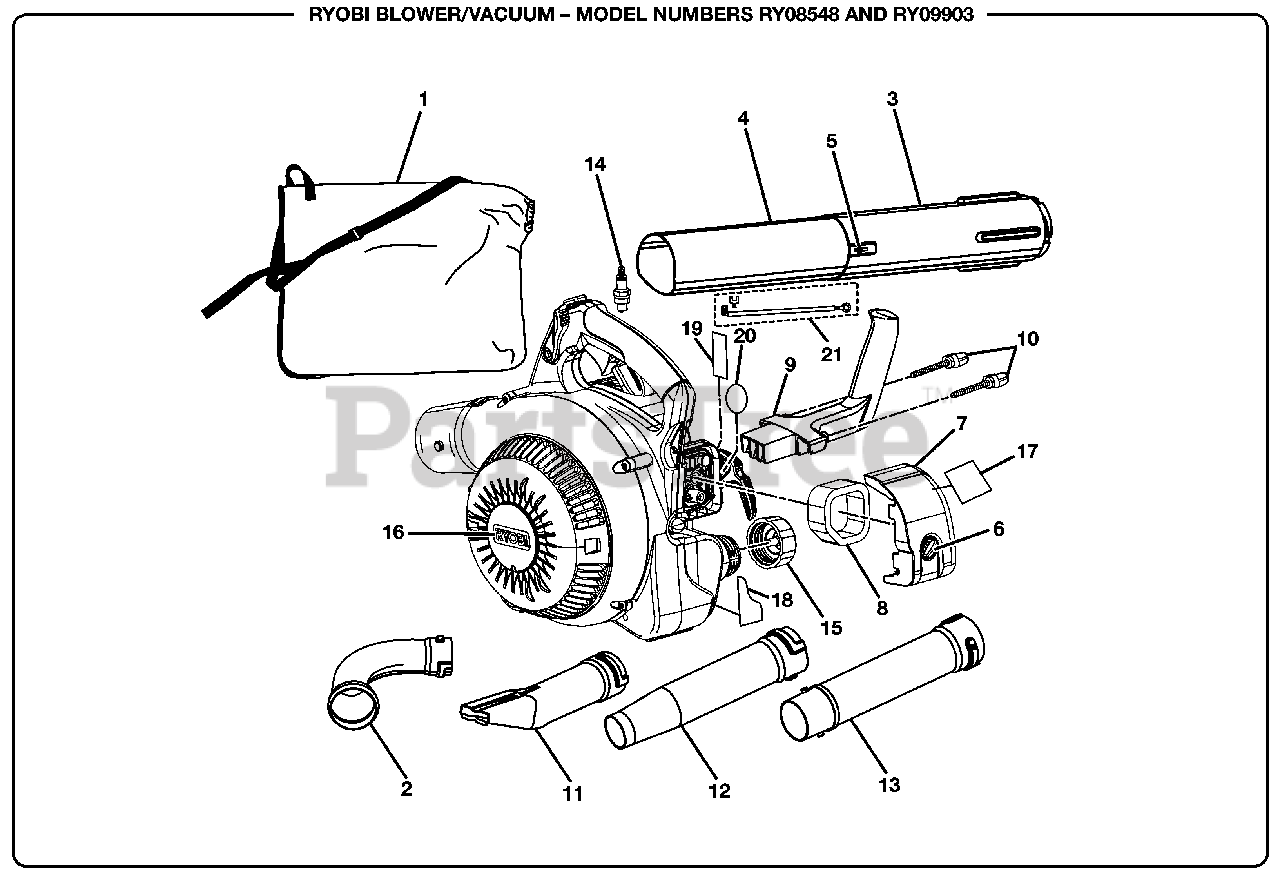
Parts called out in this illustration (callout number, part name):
1	Vacuum Bag w/Shoulder Strap
2	Vacuum Bag Adaptor
3	Upper Vacuum Tube
4	Lower Vacuum Tube
5	Vacuum Tube Screws
6	Air Filter Knob
7	Air Filter Cover
8	Air Filter
9	Vacuum Handle
10	Vacuum Handle Knobs
11	High Velocity Nozzle w/Leaf Scraper
12	Sweeper Nozzle
13	Upper Blower Tube
14	Spark Plug
15	Fuel Cap Assembly
16	Vacuum Door Label
17	Starting Instructions Label
18	Warning Label
19	Starting Label
20	Zip Start Label
21	Ground Wire Kit
